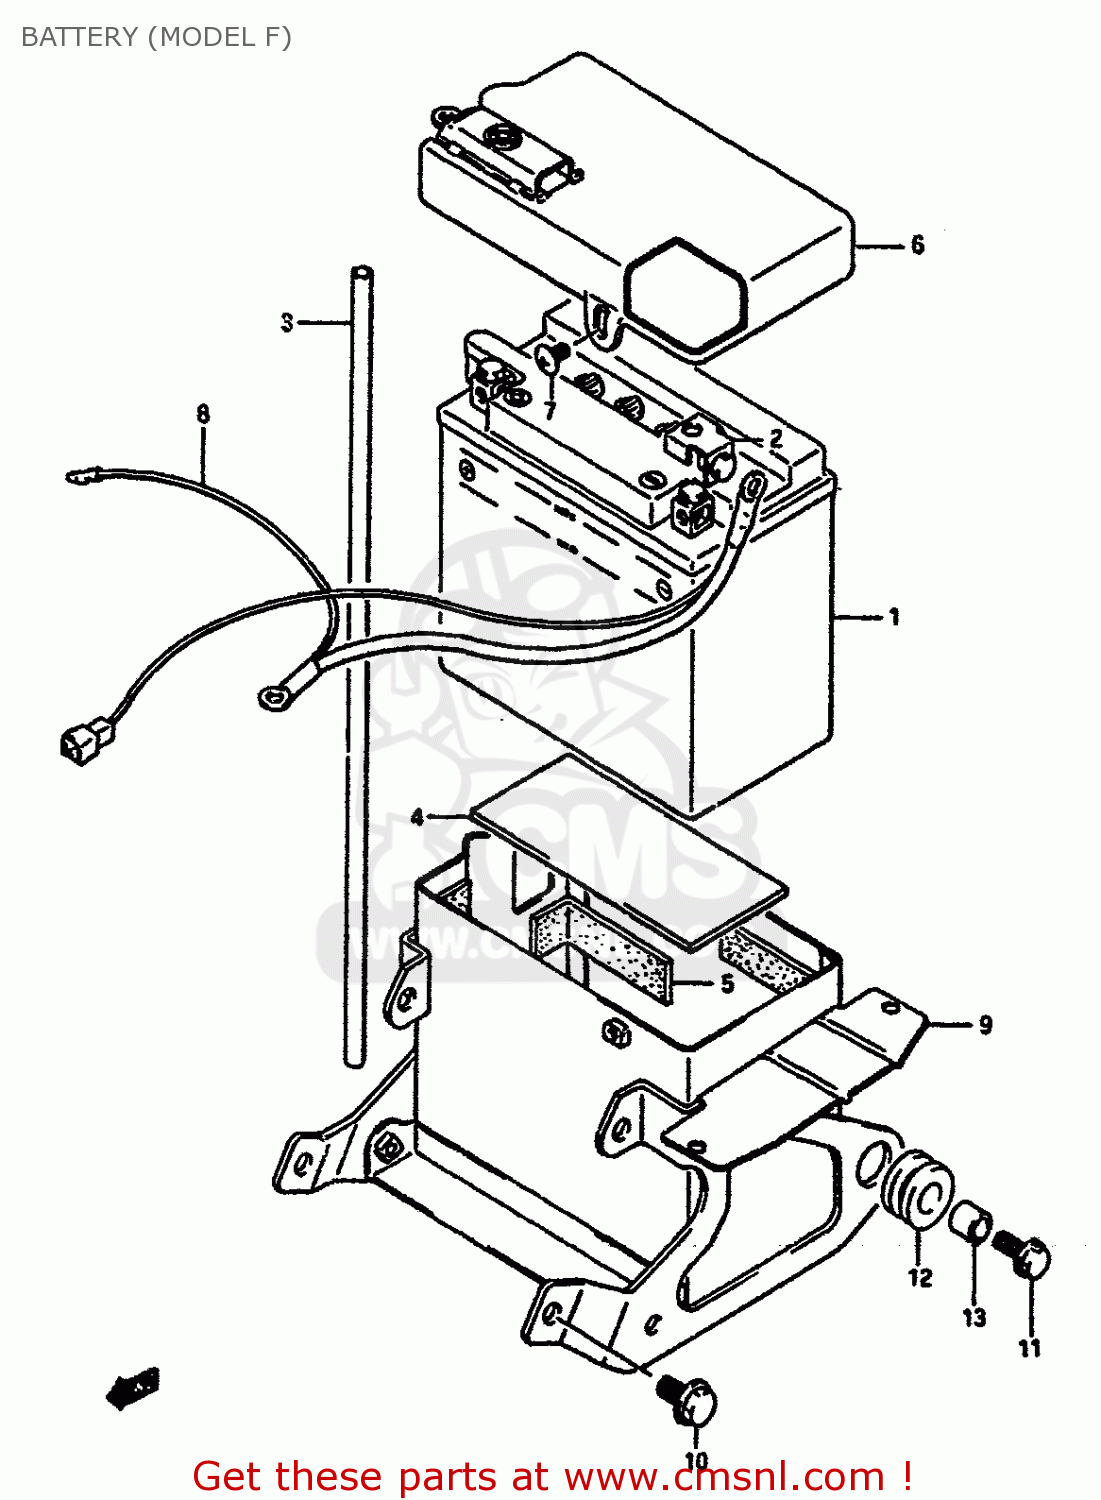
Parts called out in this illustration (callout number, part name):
1	BATTERY ASSY (12V)
2	TERMINAL,BATTERY
3	HOSE,BATTERY EXHAUST
4	PROTECTOR(170X95X3.0)
5	PROTECTOR(20X90)X2
6	COVER,BATTERY,UPPER
7	SCREW
8	WIRE,BATTERY MINUS LEAD
9	HOLDER,BATTERY
10	BOLT
11	BOLT
12	CUSHION
13	SPACER (8.8X12X11)
